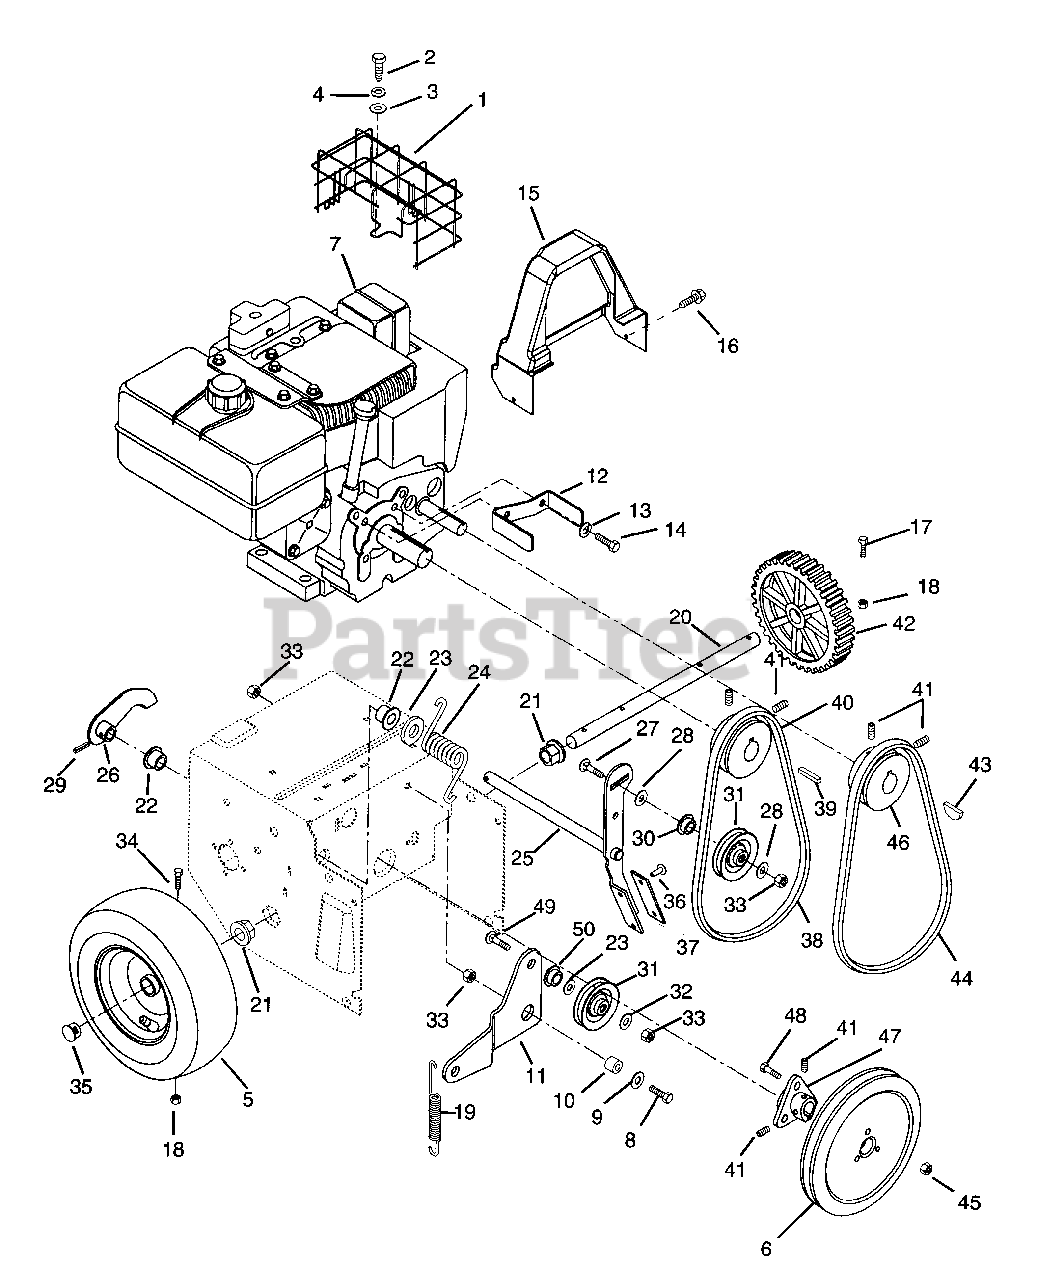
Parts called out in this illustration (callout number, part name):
1	MUFFLER GUARD 5 HP
2	SCR-TAP 10-16X.75 YWZC
3	@WSHR-FL-STL.219X.50X.049 YWZC
4	@WSHR-LK #10X.047 REG YWZC
5	WHEEL -
5	TIRE
5	TIRE/WHEEL ASSY
6	PLY-V 8.0 X 1.25 3BLT SALEM
7	5HP TECUMSEH
7	7HP TECUMSEH OHV REGENCY
8	@BLT-HEX .31-18X.75 GR5 YWZC
9	@WSHR-FL-STL.38X.875X.083 YWZC
10	SPACER BUSHING .5 X .32 X .163
11	IDLER ARM
12	BELT FINGER
12	FINGER, BELT
13	@WSHR-LK .31X.078 REG YWZC
14	BLT-HEX .31-24X.75 YWZC GR5
15	COVER, BELT
16	@SCR-TAP .25-20X.37 HWH YWZ TR
17	BLT-HEX .25-20X1.75 GR8 YWZC
18	@NUT-LK-CTR .25-20 YWZC
19	SG-TENS .047X.44X3.37 WLD 1.47
20	AXLE SHAFT
21	BSHG-FLG .750X.873HEXX.53X1.18
22	BSHG-FLG.500X.625X.312X.750NY
23	WSHR-FL-STL .520X.810X.033YWZC
24	SG-TORS .148X1.0X1.53
25	CLUTCH ARM W/BRAKE PAD
26	ARM-CLUTCH
27	@BLT-RDHDSQNK .31-18X1.25 G5YZ
28	@WSHR-FL-STL.38X.875X.083 YWZC
29	PIN-ROLL .156X.88
30	SPCR, BRG .315X.50X.688X.281
31	IDLER
32	@WSHR-FL-STL.38X.875X.083 YWZC
33	@NUT-LK-CTR .31-18 YWZC
34	BLT-HEX .25-20X1.75 GR8 YWZC
35	HOLE PLUG
36	RVT-TBLR .187X.437 RH ST PL
37	BRAKE LINING
38	V-BELT, 4L-RAW EDGE
39	KEY-SQ .188X1.0X.188 SAE 8630
40	SHEAVE-ENGINE
40	SHEAVE - ENGINE
41	SCR-SET .31-18X.38 SKHCUPDL
43	KEY-WDRF .125X.625X.250 SAE5
44	V-BELT, 3L-COGGED
45	@NUT-SPNLK-FLG .312-18 YWZC
46	SHEAVE - CAMSHAFT
48	BLT-SERRDHD SL .31-18X.75 YZ
49	@BLT-RDHDSQNK .31-18X1.25 G5YZ
50	BSHG, FLG .325X.499X.26X.88
